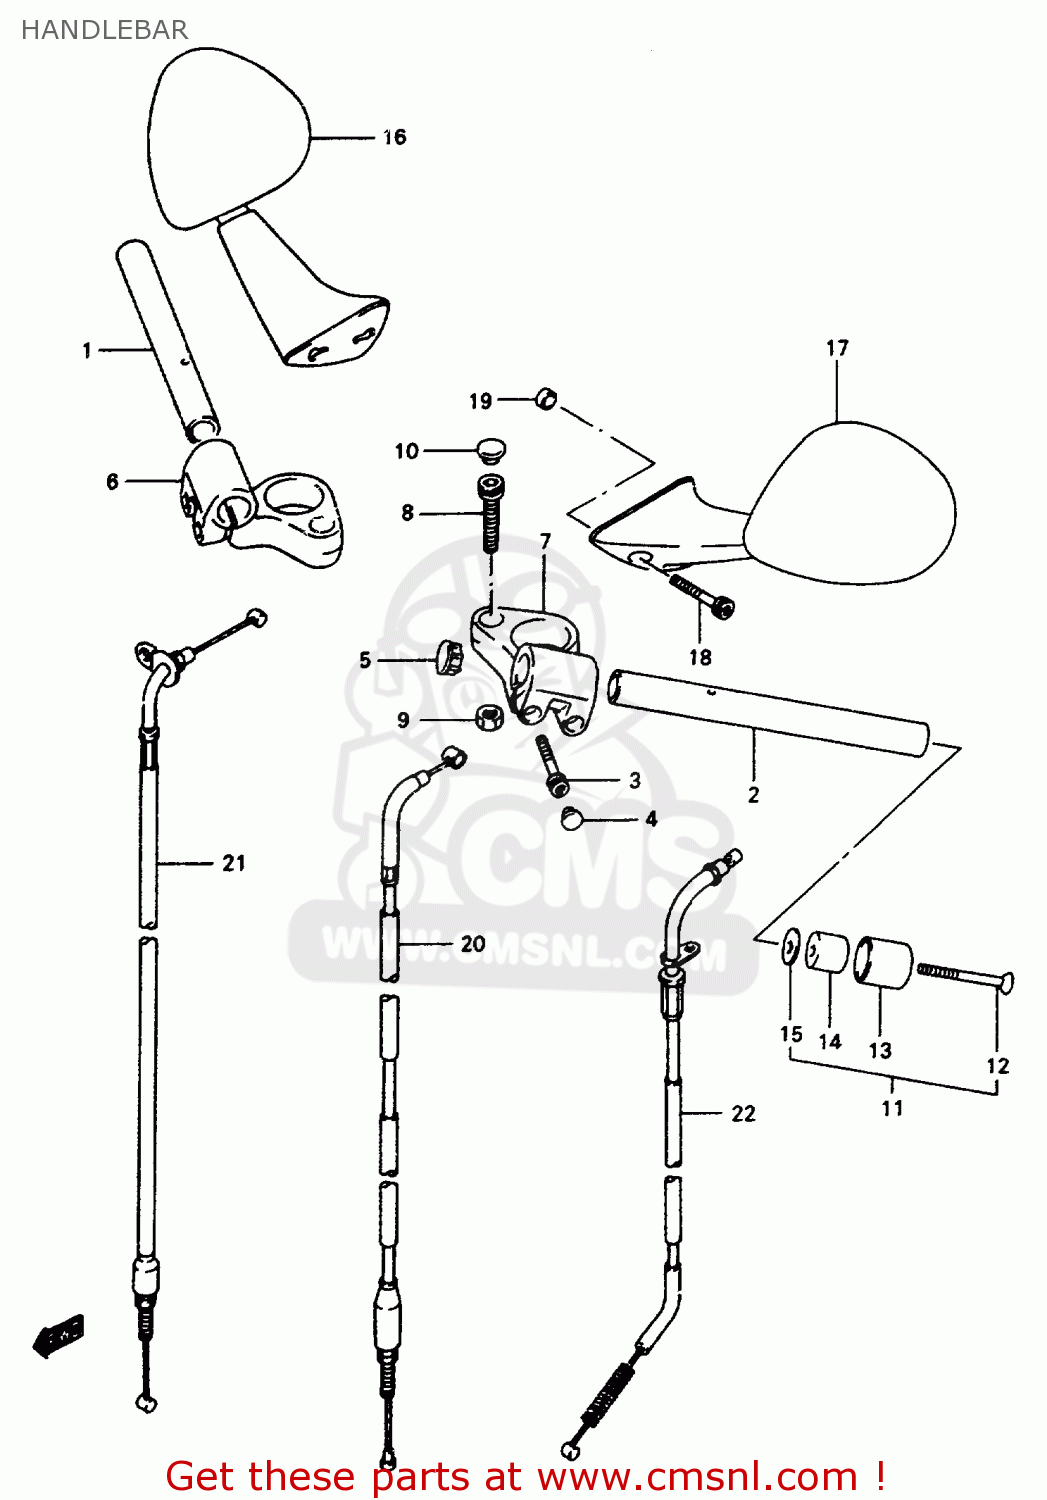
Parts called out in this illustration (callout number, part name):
1	HANDLEBAR,R
2	HANDLEBAR,L
3	BOLT
4	CAP(OD:10)
5	CAP,HANDLEBAR
6	HOLDER,HANDLE,RIGHT
7	HOLDER,HANDLE,LEFT
8	BOLT 10X45
9	NUT
10	CAP(OD:20)
11	BALANCER SET,HANDLEBAR
12	SCREW
13	CAP,BALANCER
14	BALANCER,HANDLE
15	SPACER,BALANCER
16	MIRROR ASSY,RH
17	MIRROR ASSY,LH
18	BOLT
19	SPACER(6.5X9X3.8)
20	CABLE ASSY,CLUTCH
21	CABLE ASSY,THROTTLE
22	CABLE,STARTER
